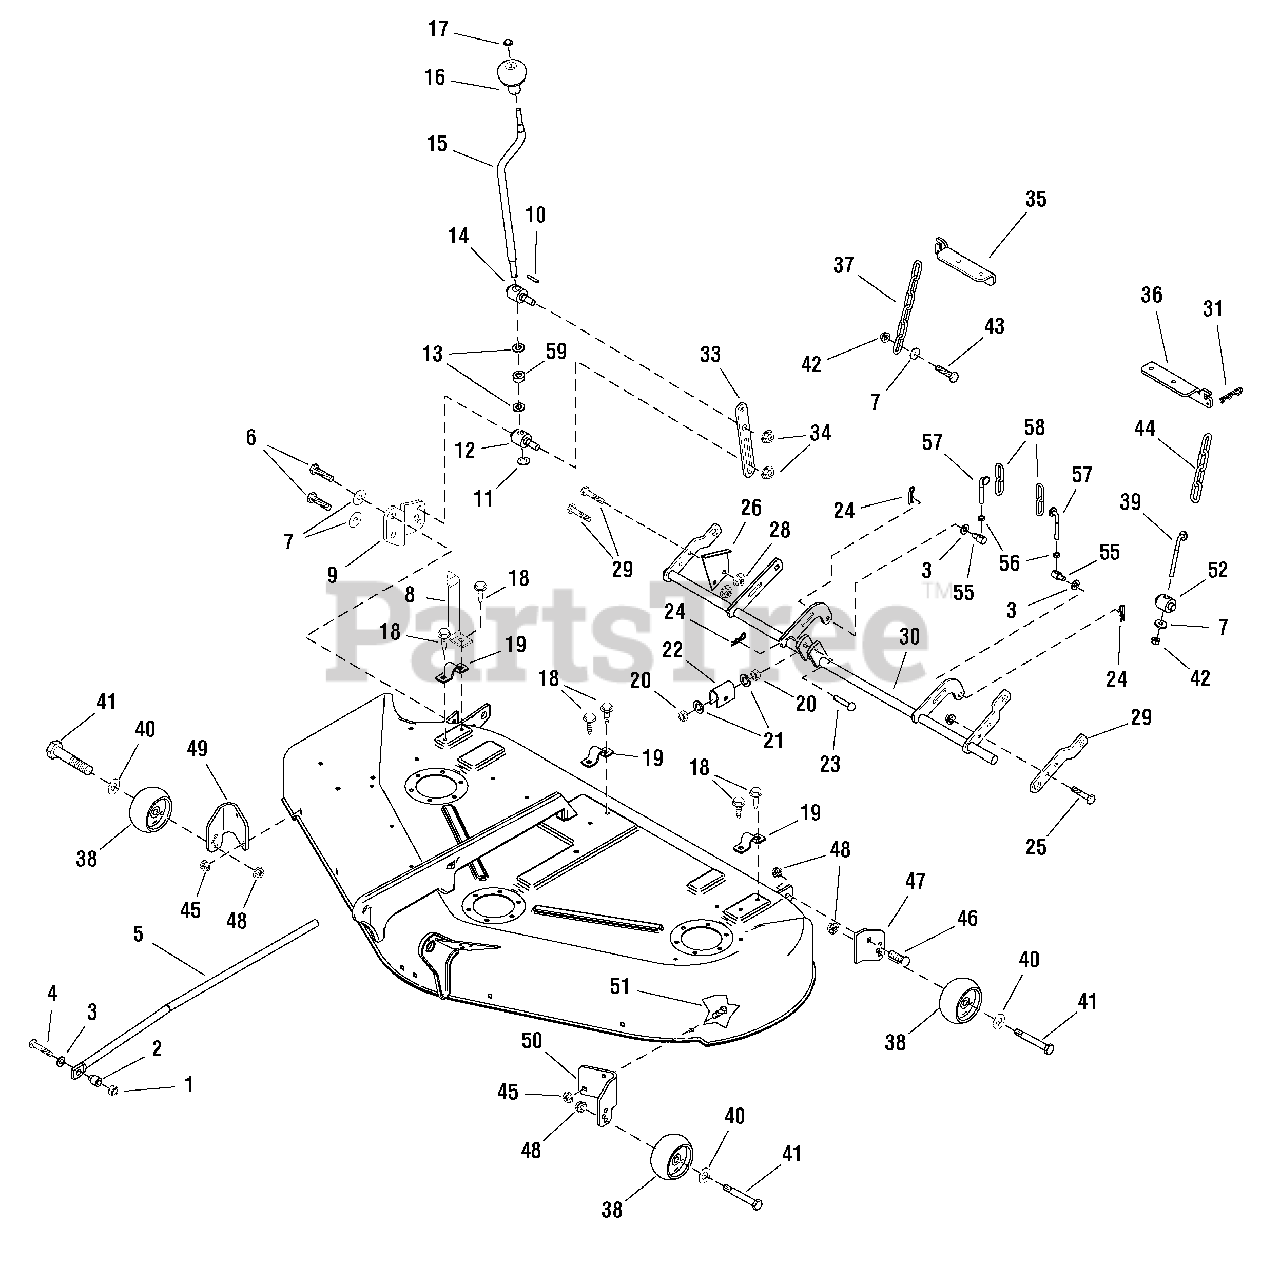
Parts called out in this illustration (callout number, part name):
1	NUT, Hex Toplock Spiralock Flange, 3/8-16
2	SPACER, 3/8 x 3/4 x 15/16
3	WASHER, 3/4
4	CAPSCREW, Hex Head 3/8-16 x 1-3/4 G8
5	ROD, Adjusting
6	SCREW, Hex Washer Head Taptite 5/16-18 x 1
7	WASHER, 5/16
8	INDICATOR, Cutting Height
9	SUPPORT, Roller, R.H.
10	PIN, Spring
11	WASHER, Detent
12	TRUNNION, 1-1/4
13	WASHER, 1/2
14	TRUNNION, L.H. Thread, 1-1/4
15	CRANK, Height Adjustment
16	KNOB, Spinner
17	NUT, Push Pal 3/8 Stud Capped
18	SCREW, Hex Washer Head Taptite 5/16-18 x 3/4
19	STRAP
20	NUT, Hex 5/8-11
21	WASHER, 5/8
22	TRUNNION
23	PIN, Round Head Drilled 3/8 x 2
24	CLIP, Hair Pin
25	CAPSCREW, Hex Head 5/16-18 x 1-1/4 G5
26	BRACKET, Height Of Cut 16GA
28	NUT, Hex Flange 5/16-18 Whiz Lock Small
29	ARM, Rear R.H.
30	SHAFT ASSEMBLY, Rocker
31	CLIP, Hair Pin
33	STOP, Height Adjusting
34	NUT, Hex Flange 1/2-13 Two-Way Lock
35	HANGER, RH
36	HANGER, LH
37	CHAIN, Link
38	WHEEL
39	ROD, Height Adjusting
40	WASHER, 1/2
41	BOLT, Wheel 3/8-16
42	NUT, Hex Flange 5/16-18
43	CAPSCREW, Hex Head 5/16-18 x 1-1/2 G8
44	CHAIN, Link
45	NUT, Hex Flange 5/16-18 Whiz Lock Large
46	CARRIAGE BOLT, 3/8-16 x 1 G5
47	SUPPORT, Roller L.H.
48	NUT, Hex Flange 3/8-16 ESNA
49	BRACKET, Wheel Gauge R.H.
50	BRACKET, Wheel Gauge L.H.
51	CARRIAGE BOLT, 5/16-18 x 7/8 G5
52	TRUNNION
55	TRUNNION
56	NUT, Hex Jam 5/16-18
57	ROD, Height Adjusting 5/16-18
58	CHAIN, Link
59	SPACER, 7/16 ID, 3/4 OD x 3/8
